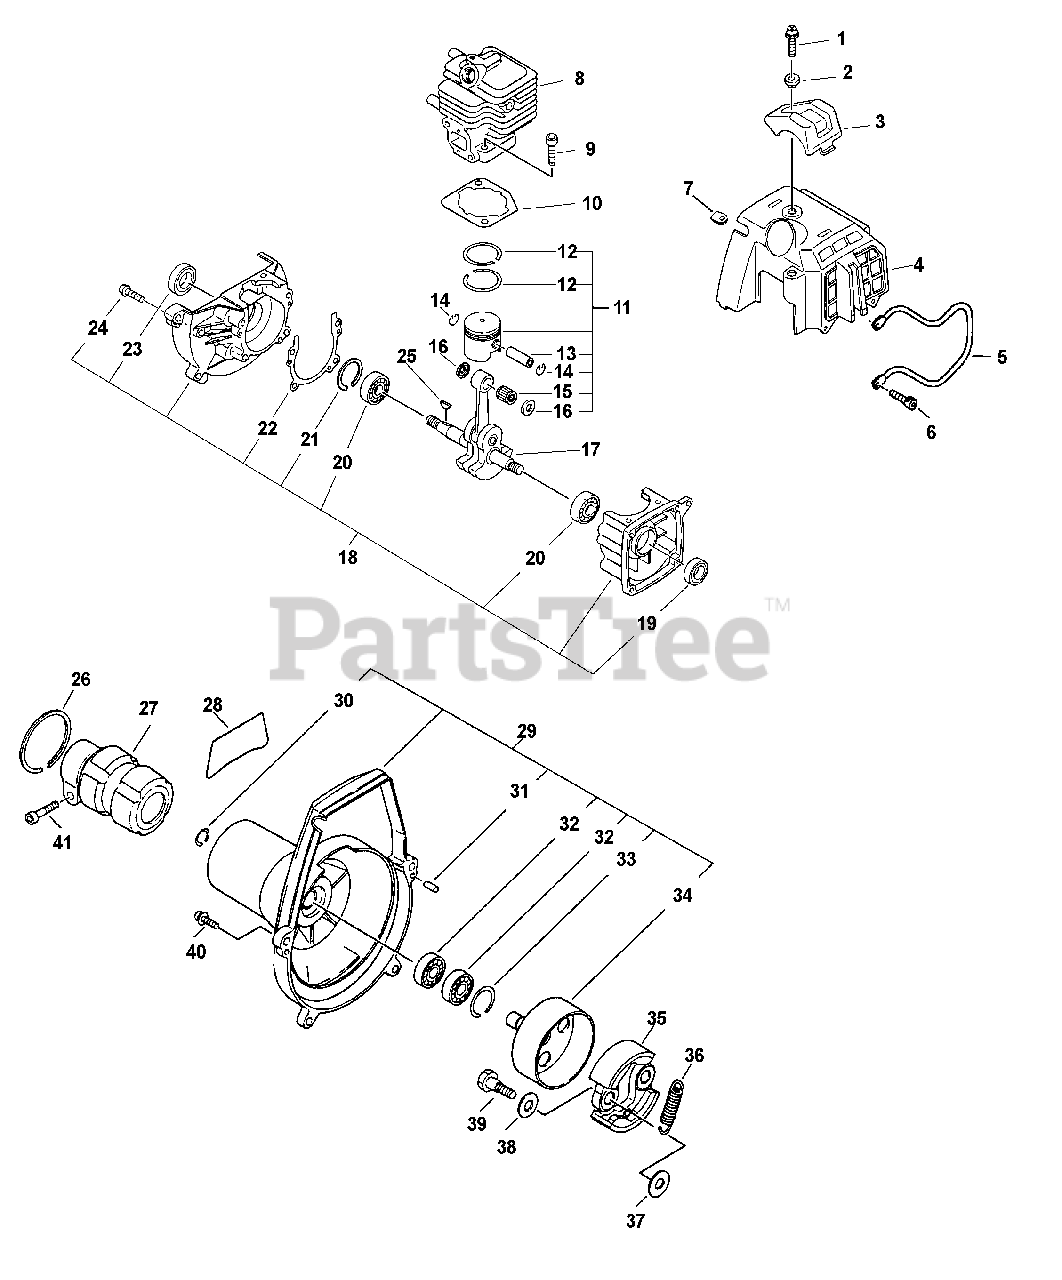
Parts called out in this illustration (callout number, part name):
1	SCREW - 5X22
2	COLLAR - 5
3	GUARD - TOP
4	COVER, ENGINE
5	GUARD, ENGINE
6	SCREW - 4X16
8	CYLINDER
9	SCREW - 5X22
10	GASKET, CYLINDER
11	PISTON KIT
12	RING, PISTON
13	PIN, PISTON
14	RING, RETAINING
15	BEARING, NEEDLE
16	SPACER, PISTON
17	CRANKSHAFT ASSY
18	CRANKCASE KIT
19	SEAL, OIL
20	BEARING, BALL - 6001C3
21	RING, RETAINING - 28
22	GASKET, CRANKCASE
23	SEAL, OIL - 12
24	SCREW - 5X25
26	RING, RETAINING - 42
27	CLAMP, MAIN PIPE
28	LABEL - MODEL PE-2601
29	FAN CASE ASSY
30	RING, RETAINING - 12
31	PIN - LOCATING
32	BEARING, BALL - 6001
33	RING, RETAINING - 28
34	DRUM, CLUTCH
35	SHOE, CLUTCH
36	SPRING, CLUTCH
37	WASHER - 6
38	WASHER - SPRING
39	BOLT, CLUTCH
40	SCREW - 5X18
41	SCREW - 5X28
